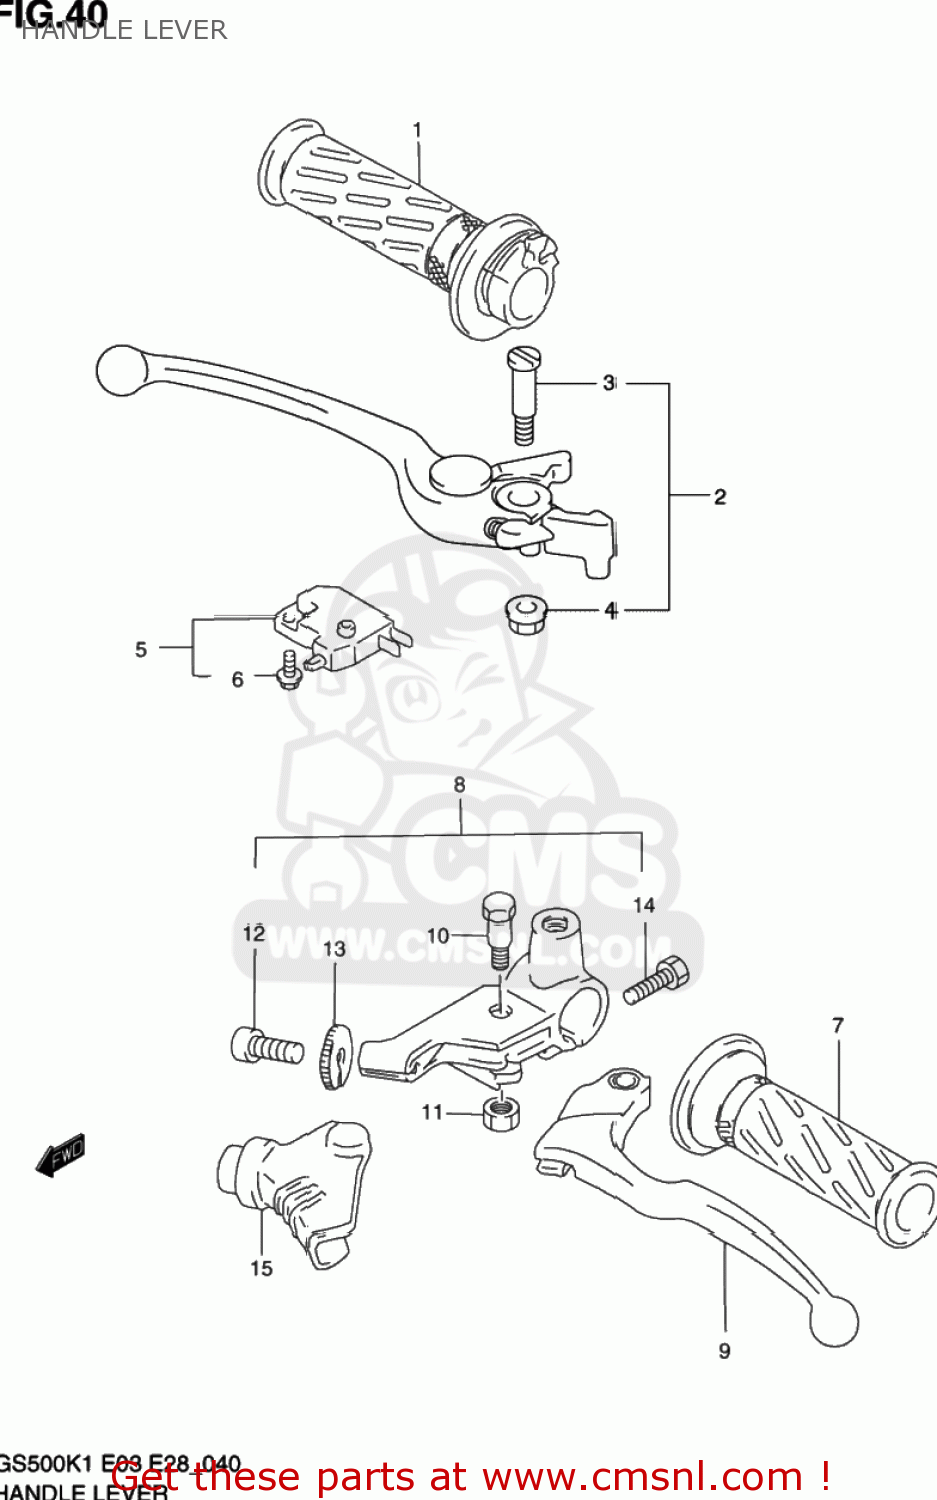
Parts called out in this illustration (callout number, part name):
1	GRIP,THROTTLE
2	LEVER ASSY,BRAKE
3	BOLT,LEVER PIVOT
4	NUT
5	SWITCH ASSEMBLY,STOP
6	SCREW
7	GRIP,LEFT
8	LEVER ASSY,CLUTCH
9	LEVER,CLUTCH
10	BOLT,LEVER SET
11	NUT
12	ADJUSTER,CABLE
13	NUT,CABLE ADJUSTER
14	SCREW
15	COVER,CLUTCH LEVER
